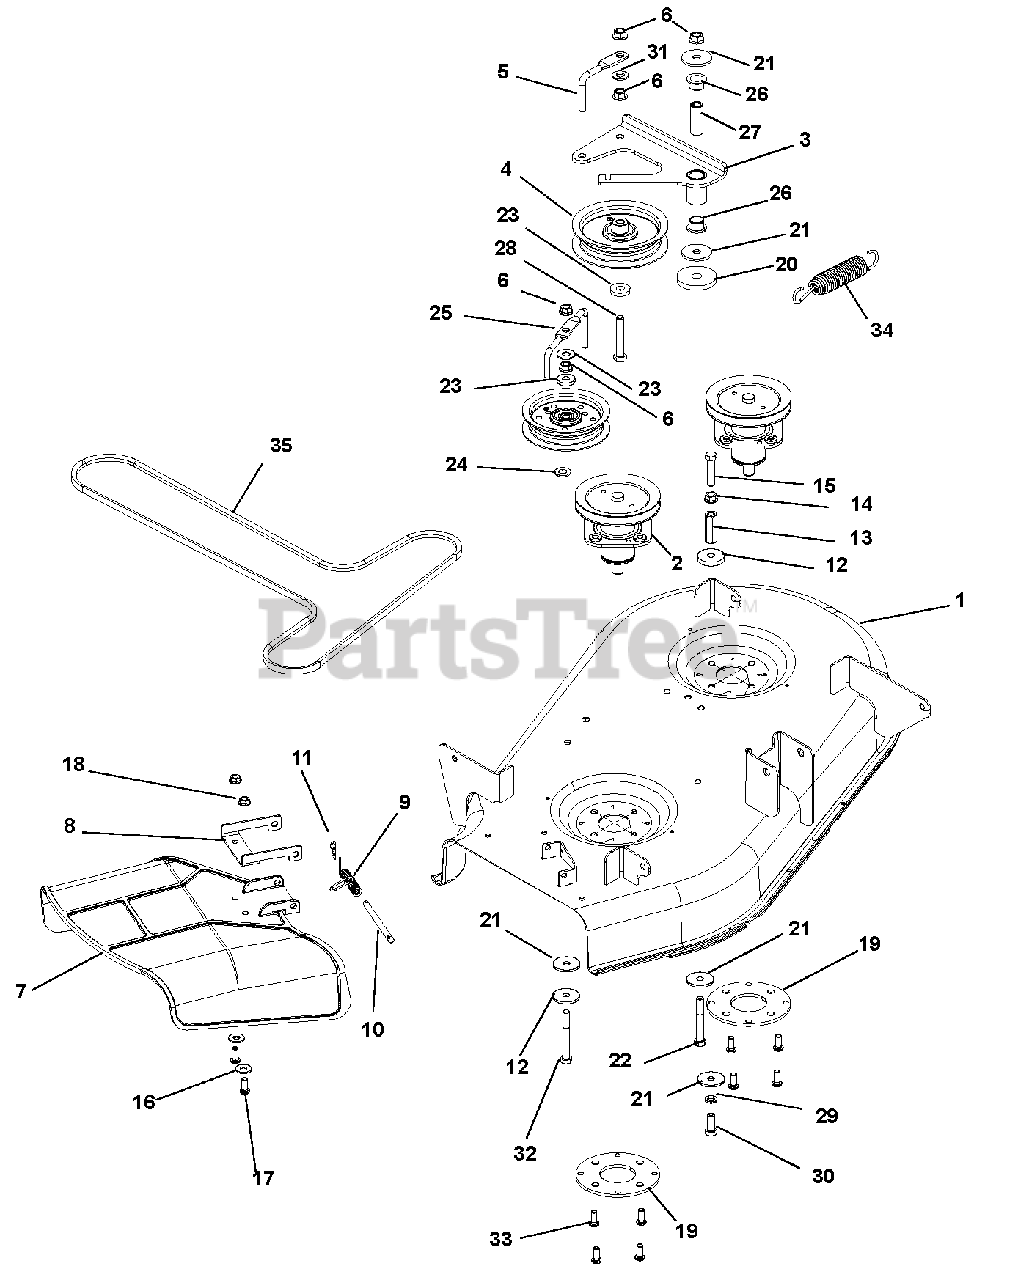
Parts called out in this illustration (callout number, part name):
1	Kit, Gravely 34" Gravely Deck
2	Assembly, Spindle
3	Weldment, Idler Arm
4	Assembly, Idler 4"
5	Wireform, Belt Finger
6	Nut, Locking Top Flange .38-16
7	Chute, Side Discharge
8	Chute Reinforcement
9	Spring, Torsion
10	Pin, 5/16 x 3.88"
11	Pin, Hair Internal .08 x .18 x 1.18
12	Washer, Flat Steel .406 x 1.50 x .245
13	Nut, Coupling .375-16 x 1.75
14	Nut, Spin Lock, Flange .375-16
15	Bolt, Hex .38-16 x 1.75
16	Washer, Flat Steel .38 x .875 x .083
17	Screw, Socket Head .31-18 x .75 Button Head
18	Nut, Locking Top Flange .31-18
19	Plate, REINF, Spindle
20	Washer, Flat Steel .469 x 2.00 x .25
21	Washer, Flat Steel .380 x 1.50 x .125
22	Bolt, Hex .38-16 x 3.00
23	Washer, Flat Steel .406 x 1.00 x .188
24	Washer, Flat Steel .438 x 1.00 x .083
25	Belt Finger
26	Bushing, Flange, .625 x .750 x .500 x 1.00
27	Spacer, .375ID x .625D x 1.66 Promaster
28	Bolt, Hex .38-16 x 2.25
29	Washer, Locking .38 x .094 Regular
30	Bolt, Hex .38-16 x 1.00
31	Washer, Flat Steel .406 x .812 x .065
32	Bolt, Hex .38-16 x 2.75
33	Screw, Tapping .38-16 x .75 Hex Washer Head Thread Rolling
34	Spring, Tension .135 x .98 x 6.0
35	V-Belt, HA-Wrapped Clutching
